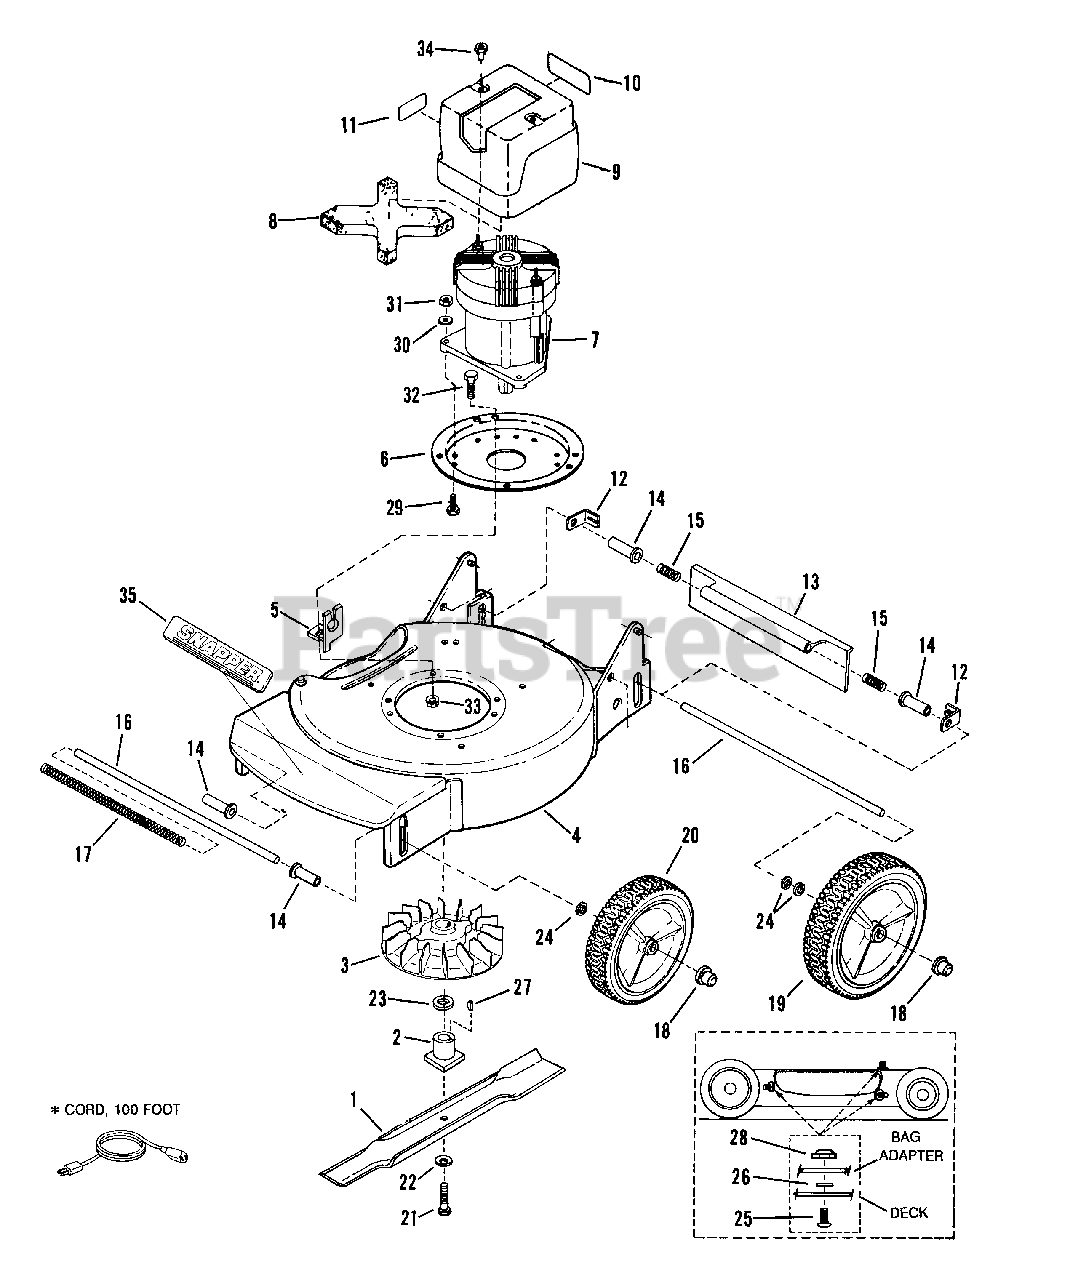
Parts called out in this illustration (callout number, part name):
1	BLADE, Cutting
2	HUB, Blade
4	DECK (Weldment)
5	CLIP, Strain Relief
10	DECAL, Grass Bag Warning
11	DECAL, Discharge Warning
12	CLIP, Guard Retaining
13	GUARD, Rear Foot
14	BUSHING, Height Adjusting
15	SPRING, Rear Axle
16	AXLE, Front & Rear
17	Spring, Front Axle
18	HUB-CAP 3/8 I.D.
19	WHEEL, Rear 8 x 2.00
20	WHEEL, Front 7 x 1.75
21	SCREW, 5/16-24 x 1-1/4" Hex Cap Gr. 5
22	WASHER, Cone
23	WASHER, 5/8 Spring
24	WASHER, 3/8" Flat
25	BOLT, 5/16-18 x 5/8" Short Neck Carriage
26	RETAINER, 5/16 Bolt
27	KEY, Square
28	NUT, 5/16-18 Hex Lock
29	SCREW, 1/4-28 x 3/4" Hex Cap
30	WASHER, 1/4 Internal Tooth
31	NUT, 1/4-28 Hex
32	SCREW, 5/16-24 x 3/4" Hex Cap
33	NUT, 5/16-24 Hex Flange Lock
34	NUT, #10-24 Hex
35	NAME PLATE, SNAPPER
